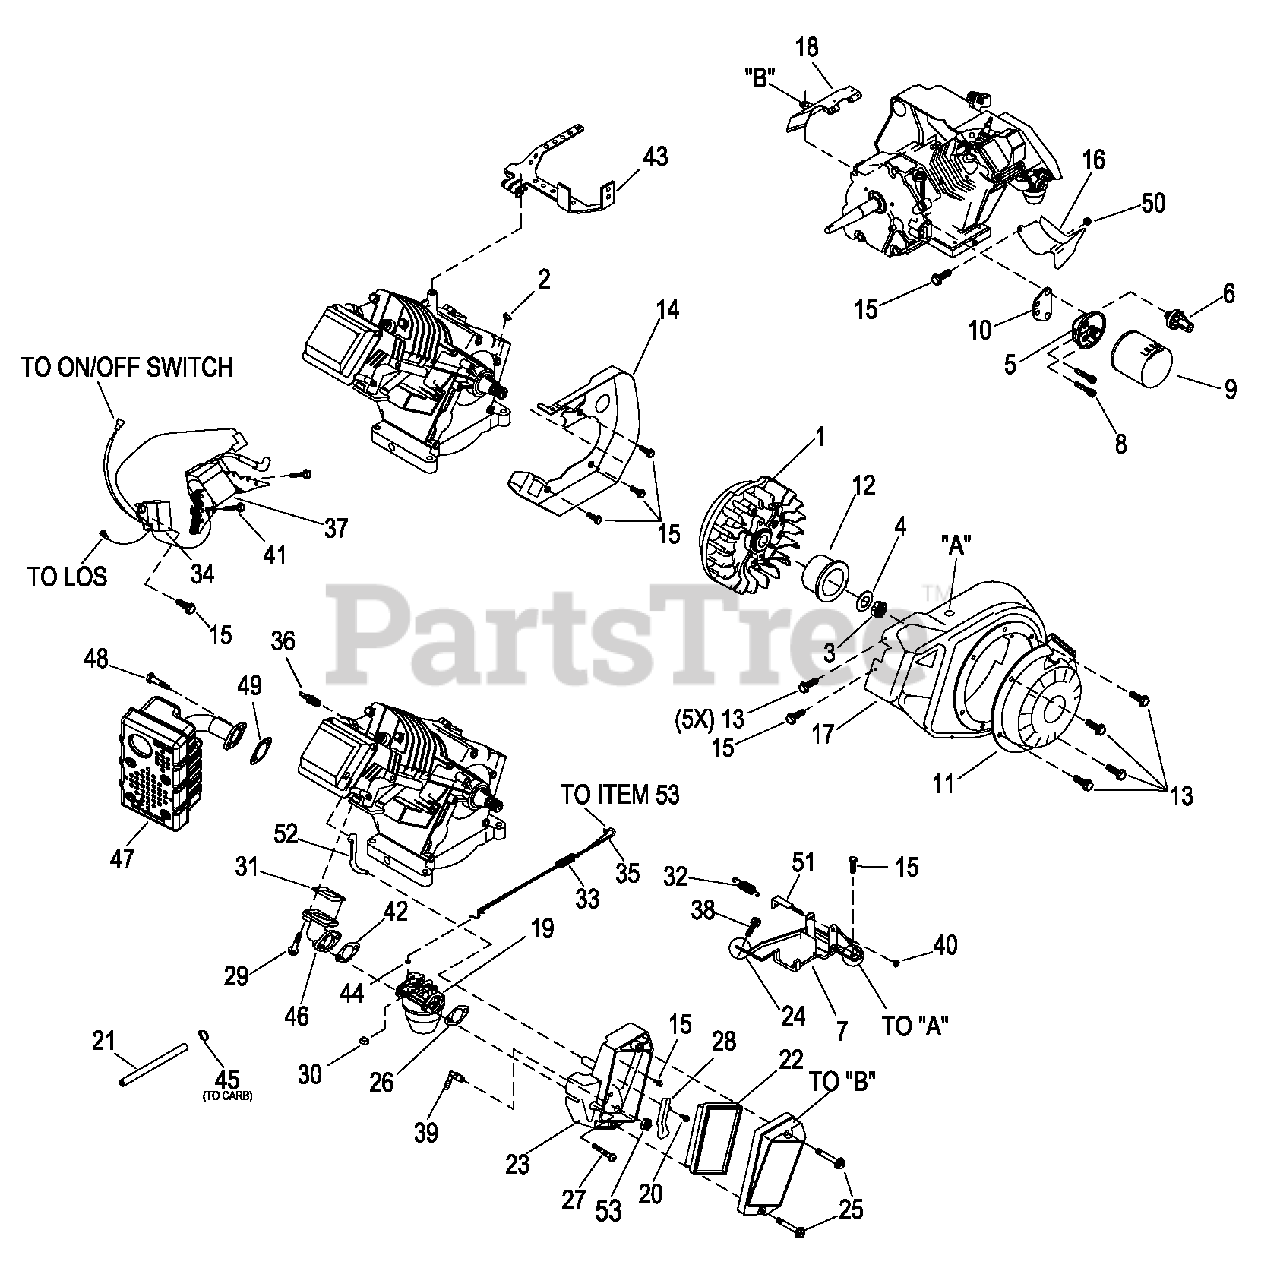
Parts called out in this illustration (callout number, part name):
1	ASSY, FLYWHEEL 29 DEGREE
2	KEY, WOODRUFF 4 X 19 DIAMETER
3	NUT, HEX M16-1.5 G8
4	WASHER, M16 CONICAL
5	ADAPTOR, OIL FILTER GH220
6	OIL PRESSURE SWITCH 5PSI
7	ASSY, BRACKET GOVERNOR ADJUSTMENT
8	SCREW, SHC M6-1.0 x 20
9	OIL FILTER BLACK 75mm LONG
10	GASKET, OIL PSI
11	ASSEMBLY, RECOIL STARTER
12	CUP, RECOIL
13	SCREW, HHTT M6-1.0 x 8
14	BACKPLATE, WITH KNOCKOUT GH220
15	SCREW, HHTT M6-1.0 x 10
16	WRAPPER, LOWER GH220
17	BLOWER HOUSING GH220
18	ASSEMBLY, TOP WRAPPER GH220
19	CARB, GH220 WITH CHOKE LEVER
20	SCREW, HHTT M5 – 0.8 X 12 BP
21	HOSE, 1/4" SAE30R11 GREENBAR 14"
22	ELEMENT, AIR CLEANER
23	BASE, AIR CLEANER W-EVAP
24	COVER, AIR CLEANER
25	SCREW, HHSFC M6-1.0 x 31
26	GASKET, CARB / MANIFOLD W/O ADHESIVE
27	BOLT, CARBURETOR MOUNTING
28	COVER, BREATHER CANAL
29	SCREW, HHFC M6-1.0 x 30
30	KNOB, CHOKE LEVER
31	GASKET, MANIFOLD / HEAD
32	SPRING, GOVERNOR (BLUE COLOR)
33	SPRING, ANTI-LASH
34	ASSY, LOS MODULE NO LED
35	ROD, GOVERNOR GH220
36	SPARK PLUG GAP: 0.030"
37	ASSY, IGNITION COIL ADVANCED NO DIODE
38	SCREW, HHTT M8-1.2 x 16
39	BARBED EL 90 1/8NPT X 1/4 NY
40	NUT, HEX LOCK M5-0.5 NYLON INSERT
41	SCREW, HHTT M6 – 1.0 X 25 ZINC
42	GASKET, CARBURETOR / AIRBOX
43	ASSEMBLY, GOVERNOR LEVER
44	WASHER, NYLON 0.12ID x 0.28OD
45	CLAMP, HOSE #5.5
46	INTAKE MANIFOLD
47	MUFFLER, GH220 SIDE-OUT
48	SCREW, SHC M8-1.25 x 20 SEMS
49	GASKET, EXHAUST
50	GROMMET, 9/16" x 1/16" X 7/16"
51	SCREW, GOVERNOR ADJUSTMENT
52	HOSE, BREATHER GH220
53	NUT HEX 1/8-27 NPS THIN
